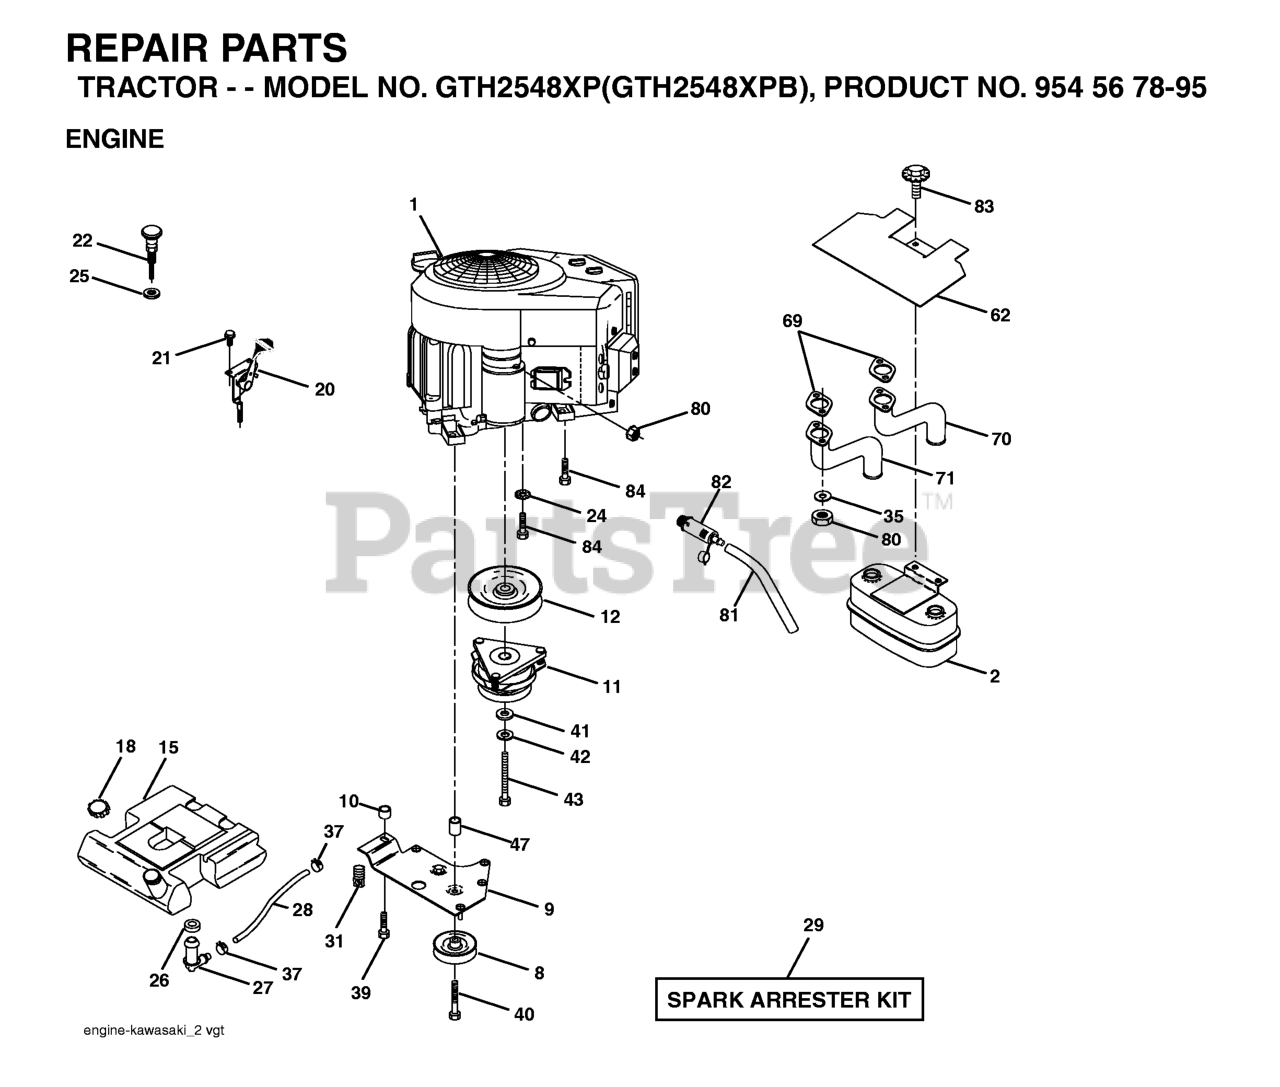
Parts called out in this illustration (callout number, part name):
2	MUFFLER.TWIN.CYL.LOW.TONE
8	RP.IDLER GROOVED
9	KEEPER ASM BELT ENGINE
11	CLUTCH MZ ZTR GT.48/54"1.125"
12	PULLEY ENG VGT ELECT CLUTCH
15	TANK.FUEL.5.0 LEFT.FILL.YTGT
18	TANK CAP
20	CONTROL.THROTTLE.COBRA.42"BLK.
21	SCREW
22	CHOKE CONTROL
24	LOCKWASHER
25	Nut Keps 3/8 - 24 UNF
26	BUSHING OUTLET T
27	STEM FUEL TANK
28	HOSE
29	KIT.SPARK ARRESTOR 794945 B&S
37	HOSE CLAMP
39	SCREW TT 3/8-16X2-1/4 UNC
40	Screw TT 3/8-16 x 4 unc
42	LOCKWASHER
43	BOLT HEX 7/16-20 X 3.75 GR. 5
62	HEAT SHIELD
70	TUBE EXHAUST LH
71	TUBE.EXHAUST.KAWASAKI.RH
80	FLANGE NUT
81	TUBE, DRAIN OIL ASM.
83	BOLT.5/16-18UNCX3/4 W/SEMS.BLK
84	SCREW 3/8-16 X 1-1/2
